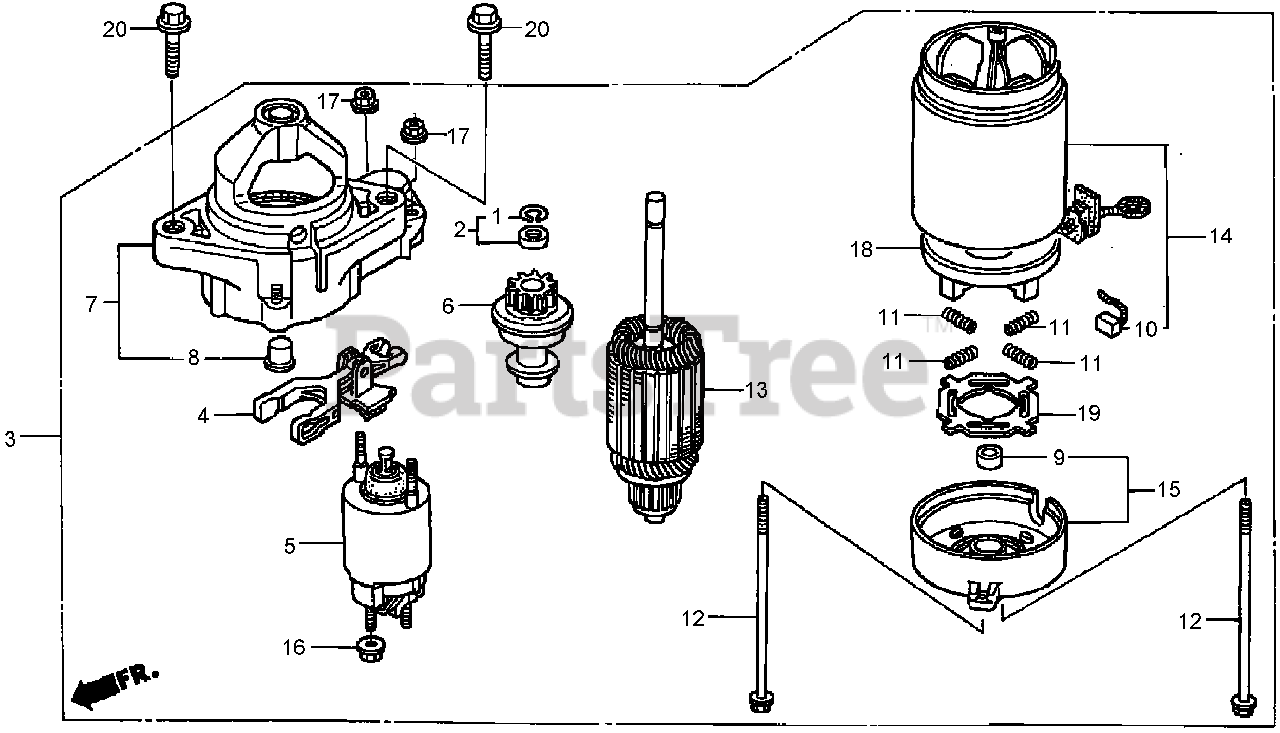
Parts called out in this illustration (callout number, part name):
1	RING-SNAP (DENSO)
2	CLUTCH STOP COLLAR SET
3	STARTER MOTOR ASM
4	LEVER-DRIVE, PINION
5	MAGNETIC SWITCH ASM
6	CLUTCH-OVERRUNNING
7	HOUSING-DRIVE SIDE
8	BEARING (A)
9	BEARING (B)
10	BRUSH
11	SPRING-BRUSH
12	BOLT-THROUGH
13	ARMATURE
14	YOKE
15	FRAME-END, COMMUTATOR
16	NUT-HEX (8MM)
17	NUT-FLANGE (5MM)
18	HOLDER-BRUSH
19	INSULATOR-HOLDER, BRUSH
20	BOLT-FLANGE (10X40)
